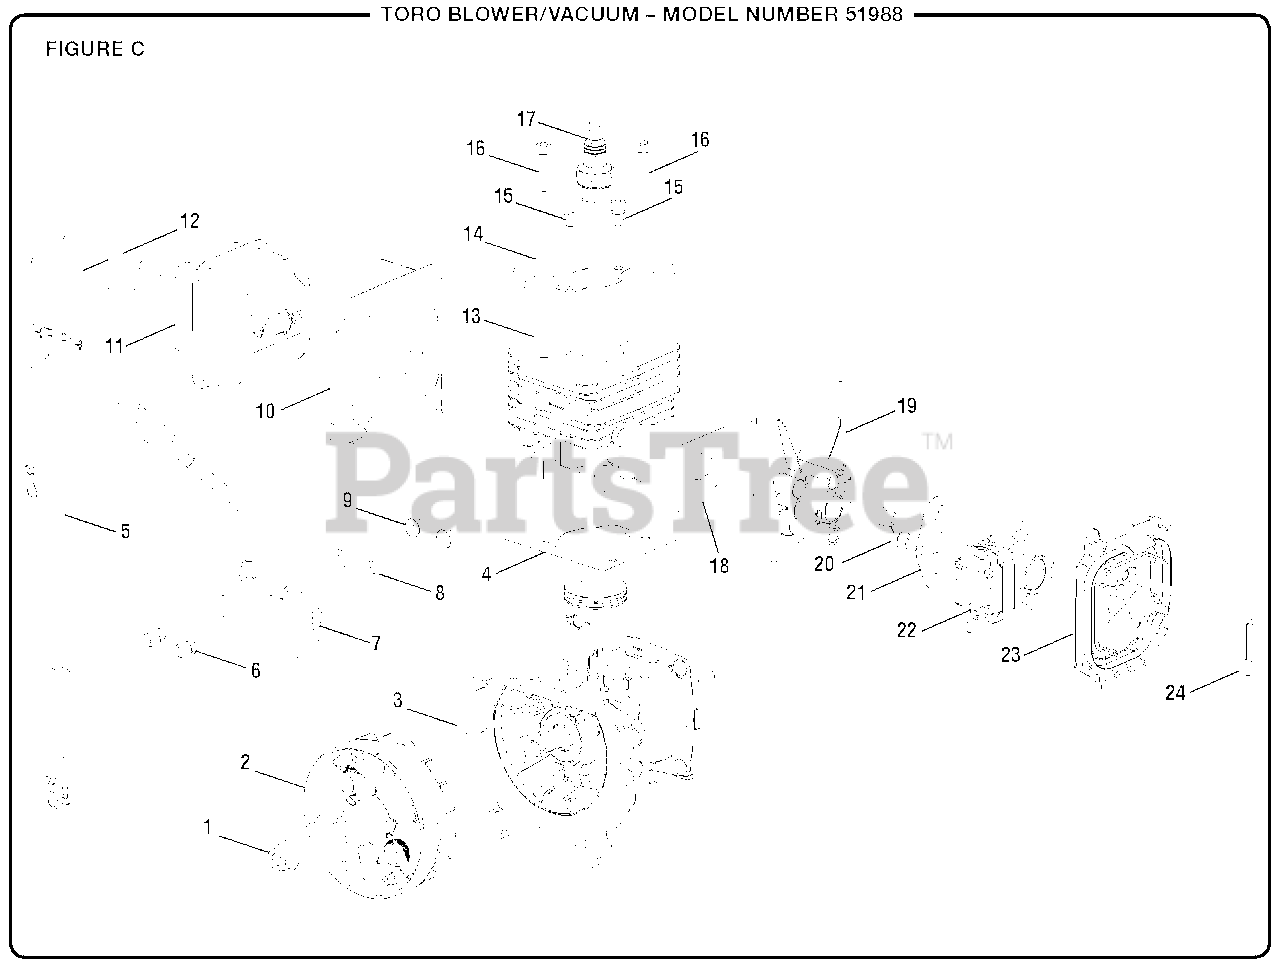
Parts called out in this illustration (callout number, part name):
1	Nut (M8)
2	Flywheel Assembly
3	Crankcase and Piston Assembly
5	Wire Harness
6	Screw (M4 x 22 mm)
7	Ignition Module
8	Washer (4.2ID x 10OD x ?t)
10	Muffler Gasket
11	Muffler Assembly
12	Screw (M5 x 65 mm, Torx T25)
14	Cylinder Plate
15	Screw w/Washer (M5 x 10 mm)
16	Screw (M5 x 22 mm)
17	Spark Plug (RCJ6Y)
18	Cylinder Gasket
19	Heat Sink
20	Screw (M5 x 27 mm, Torx T20)
21	Carburetor Gasket
22	Carburetor Assembly
23	Air Box Cover Base Assembly
24	Screw (M5 x 45 mm, Torx T25)
